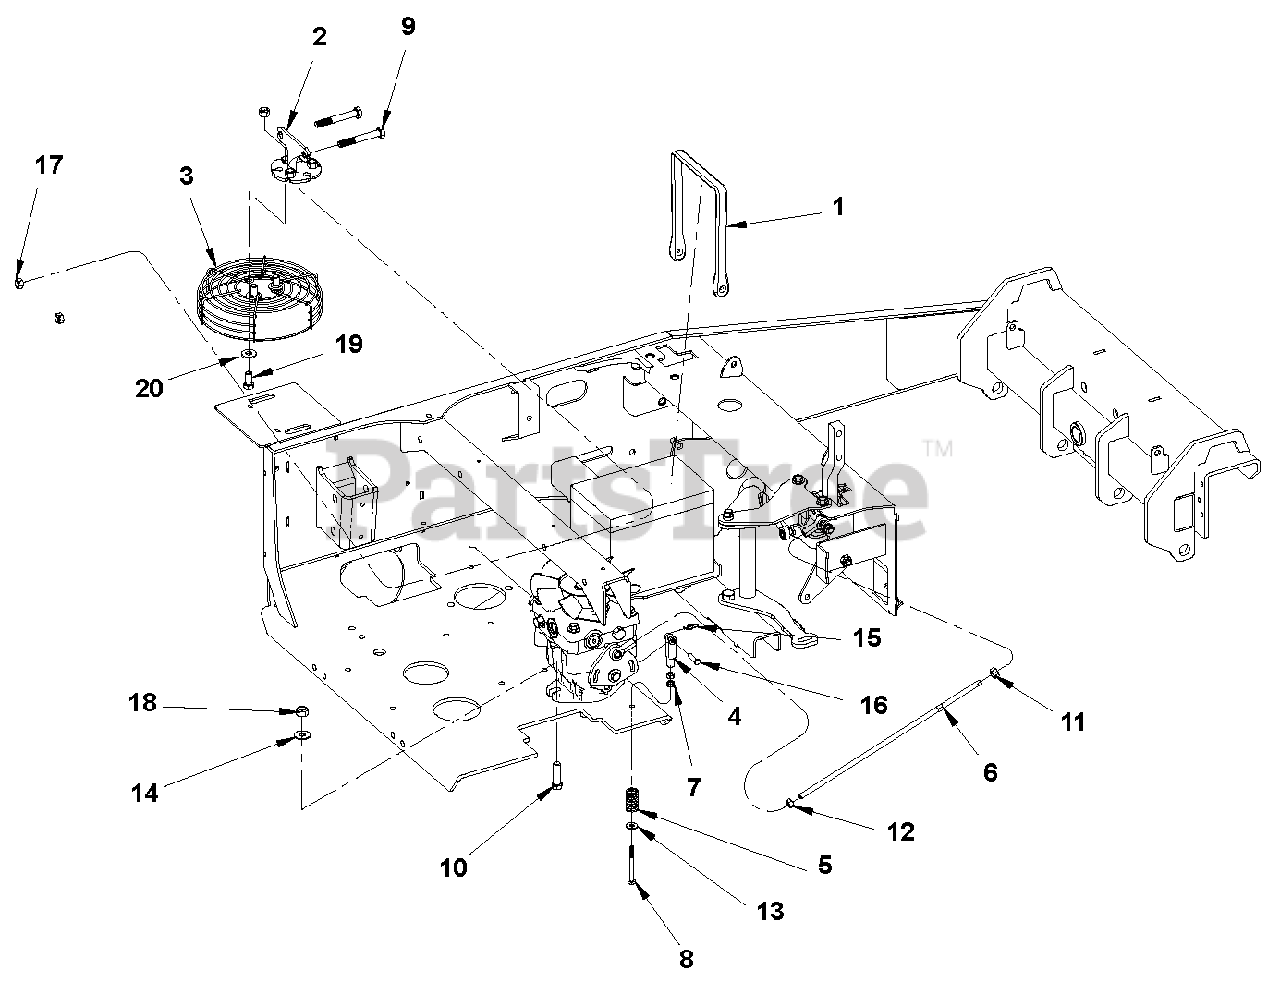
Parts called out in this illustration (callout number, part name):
1	Band, 18"
2	WLDT, FAN SHIELD MOUNTING
3	Grill, 7" Fan
4	Yoke, 1/4-20 RH Adjustable
5	Spring, Compression .784 x .092 x 1.50
6	Pump Control Rod
7	Locknut, 1/4-20 Nyloc
8	Bolt, 1/4-20 x 2.75 SOC 8
9	Bolt, 3/8-16 x 2.75 Hex 5
10	Bolt, 7/16-14 x 1.50 Hex Grade 5
11	Nut, 5/16-24 STD Hex Grade 5
12	Nut, 5/16-24 Hex Grade 5 LH
13	Washer, .250 Reg Flat
14	Washer, .375 Reg Flat
15	Ring, Rue .250 x .041 x .844
16	Pin, CVS .250 x 1.00 x .859
17	Locknut, 3/8-16 Crown
18	Locknut, 7/16-14 Crown
19	Bolt, 3/8-16 x .750 Hex
20	Washer, .313 Reg Flat
